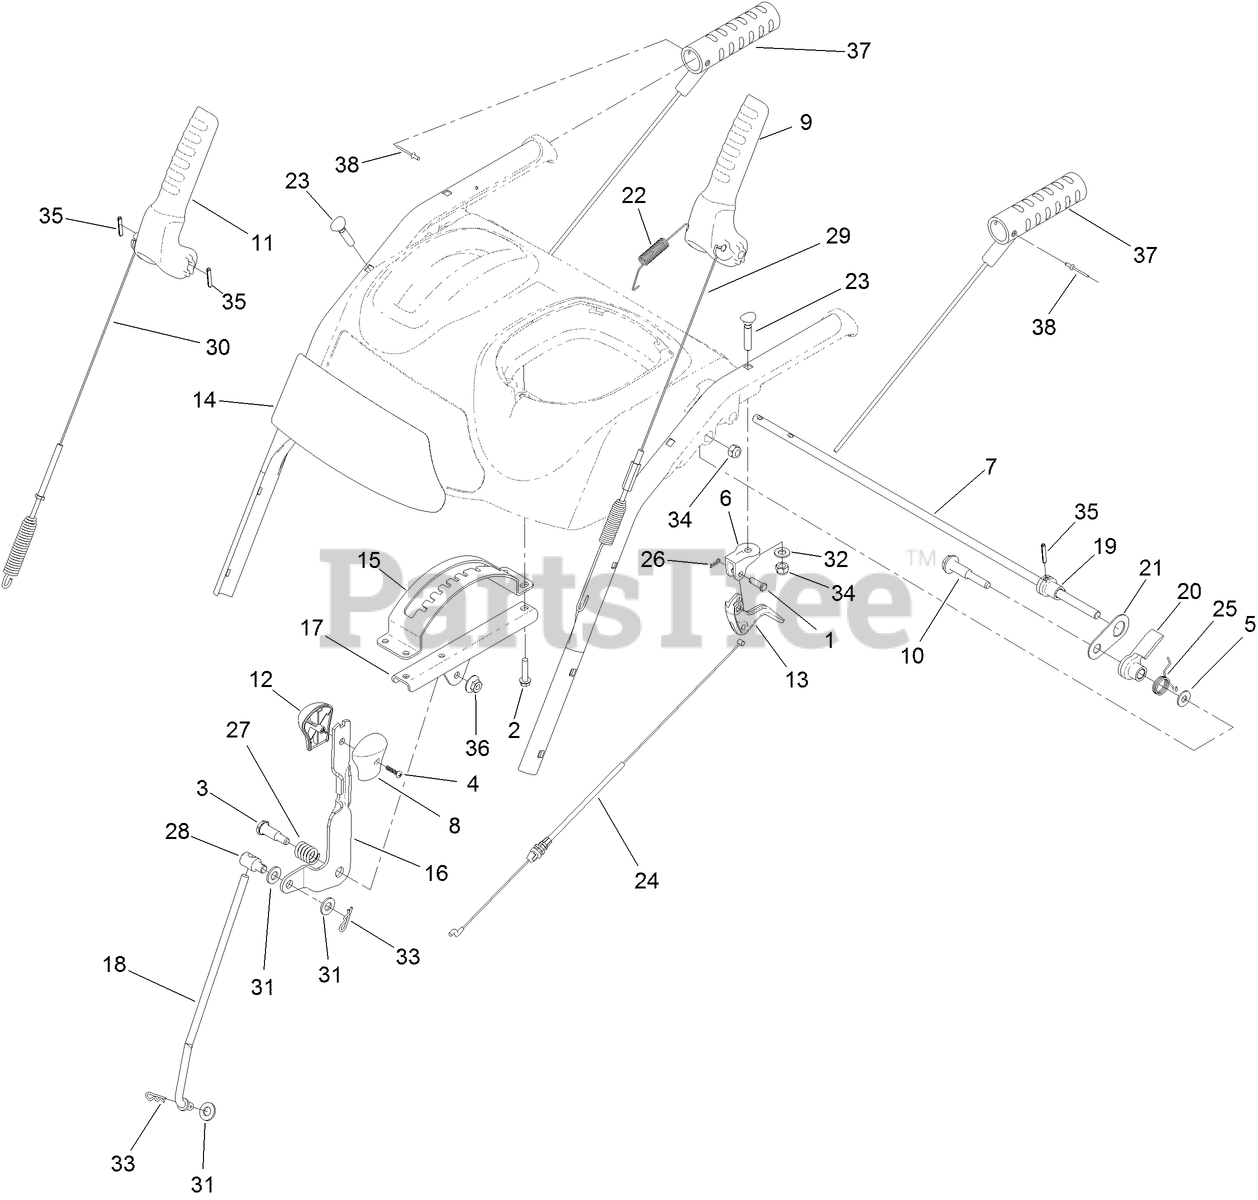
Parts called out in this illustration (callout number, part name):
1	PIN-CLEVIS
2	SCREW-PLASTITE
3	SCREW-SHOULDER
4	SCREW-PPH
5	WASHER-FLAT
6	MOUNT-CLUTCH, LEVER
7	ROD-LOCKOUT
8	KNOB-SHIFT, LH
9	LEVER-TRACTION
10	SCREW-SHOULDER
11	LEVER-AUGER
12	KNOB-SHIFT, RH
13	LEVER-CLUTCH
14	DECAL-CONTROL PANEL
15	GUIDE-SELECTOR, SPEED
16	SELECTOR-SPEED
17	BRACKET-SELECTOR, SPEED
18	ROD-SHIFT
19	CAM-LOCKOUT
20	LATCH-LOCKOUT
21	LINK-LOCKOUT
22	SPRING-TENSION
23	SCREW-HANDLE
24	CABLE-CLUTCH
25	SPRING-TORSION
26	PIN-HAIR
27	SPRING-COMPRESSION
28	TRUNNION-ROD
29	CABLE-TRACTION
30	CABLE-AUGER
31	WASHER-FLAT
32	WASHER-FLAT
33	PIN-COTTER
34	NUT-LOCK, NI
35	PIN-SPRING
36	NUT-HF
37	GRIP-HEATED
38	RIVET-POP
